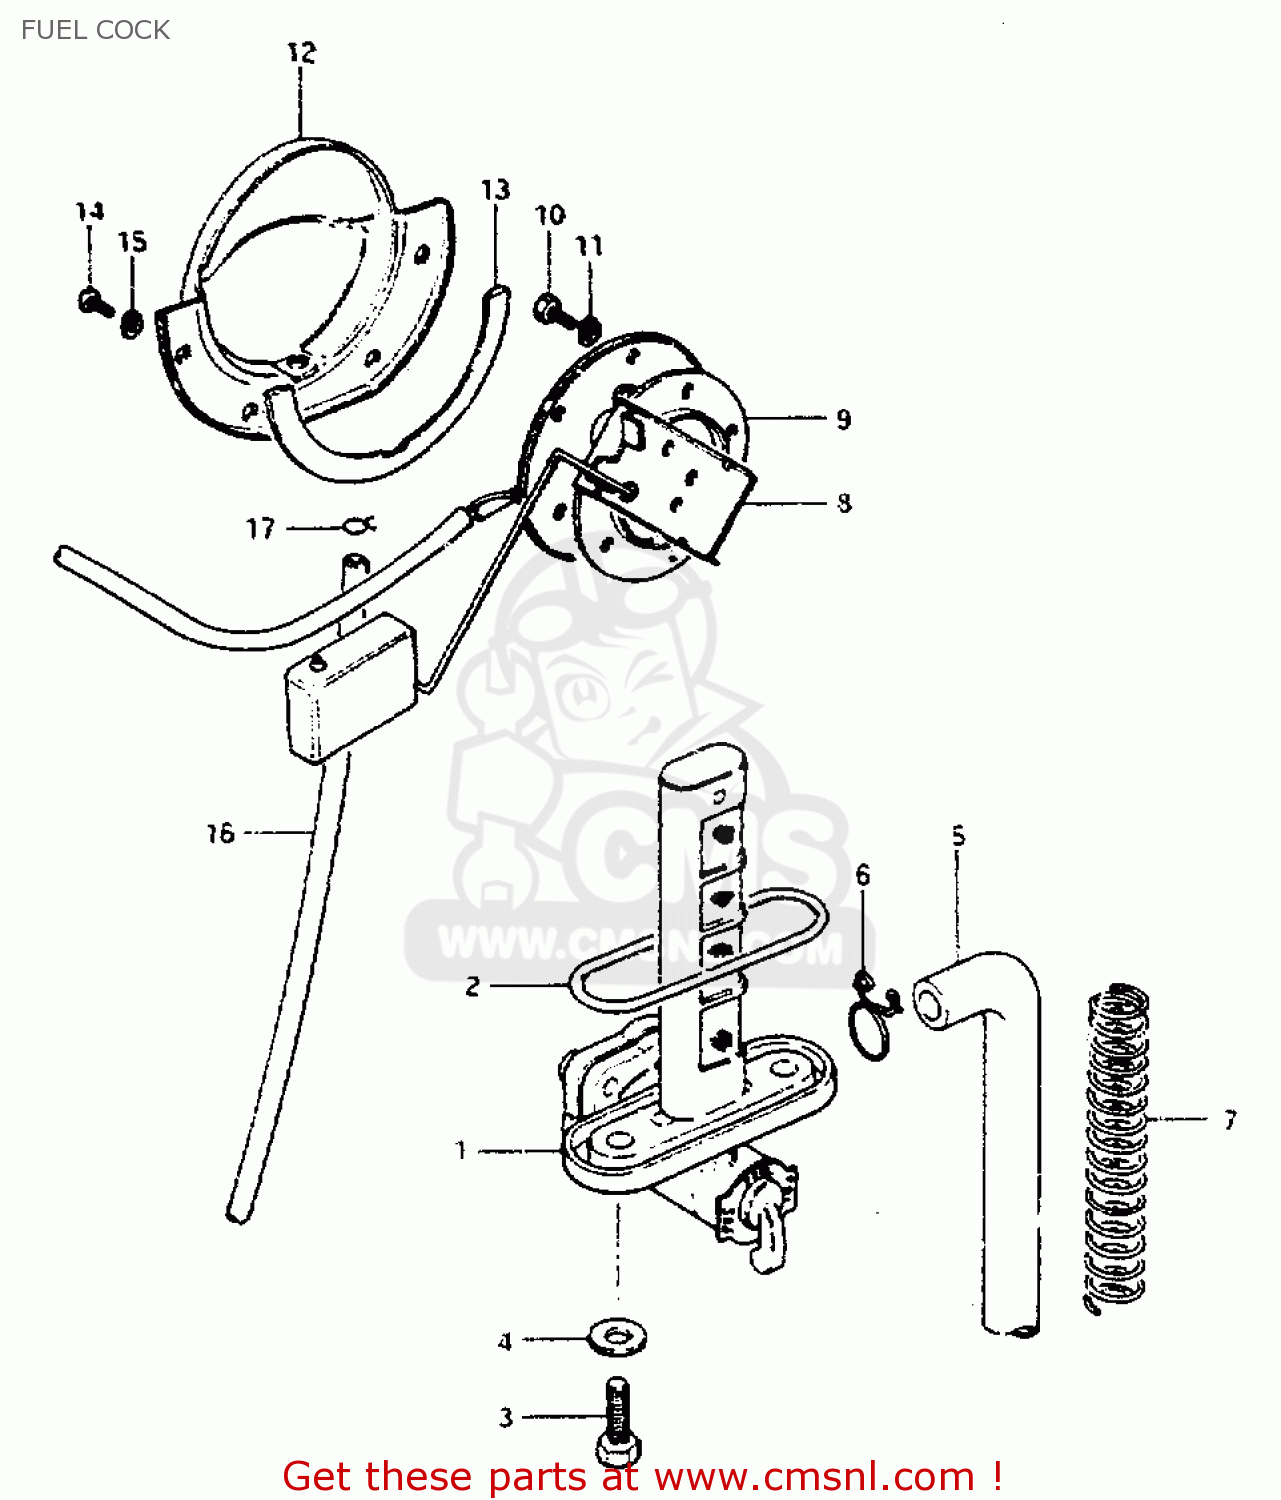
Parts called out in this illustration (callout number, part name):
1	COCK ASSEMBLY,FUEL
2	O RING
3	BOLT(6X20)
4	GASKET
5	HOSE
6	CLIP
7	SPRING
8	GAUGE ASSEMBLY,FUEL LEVEL
9	GASKET,FUEL LEVEL GAUGE (NAS)
10	BOLT
11	LOCK WASHER
12	PLATE,FUEL DRAIN
13	GASKET,FUEL DRAIN PLATE (NAS)
14	SCREW
15	LOCK WASHER
16	HOSE,FUEL
17	CLIP
